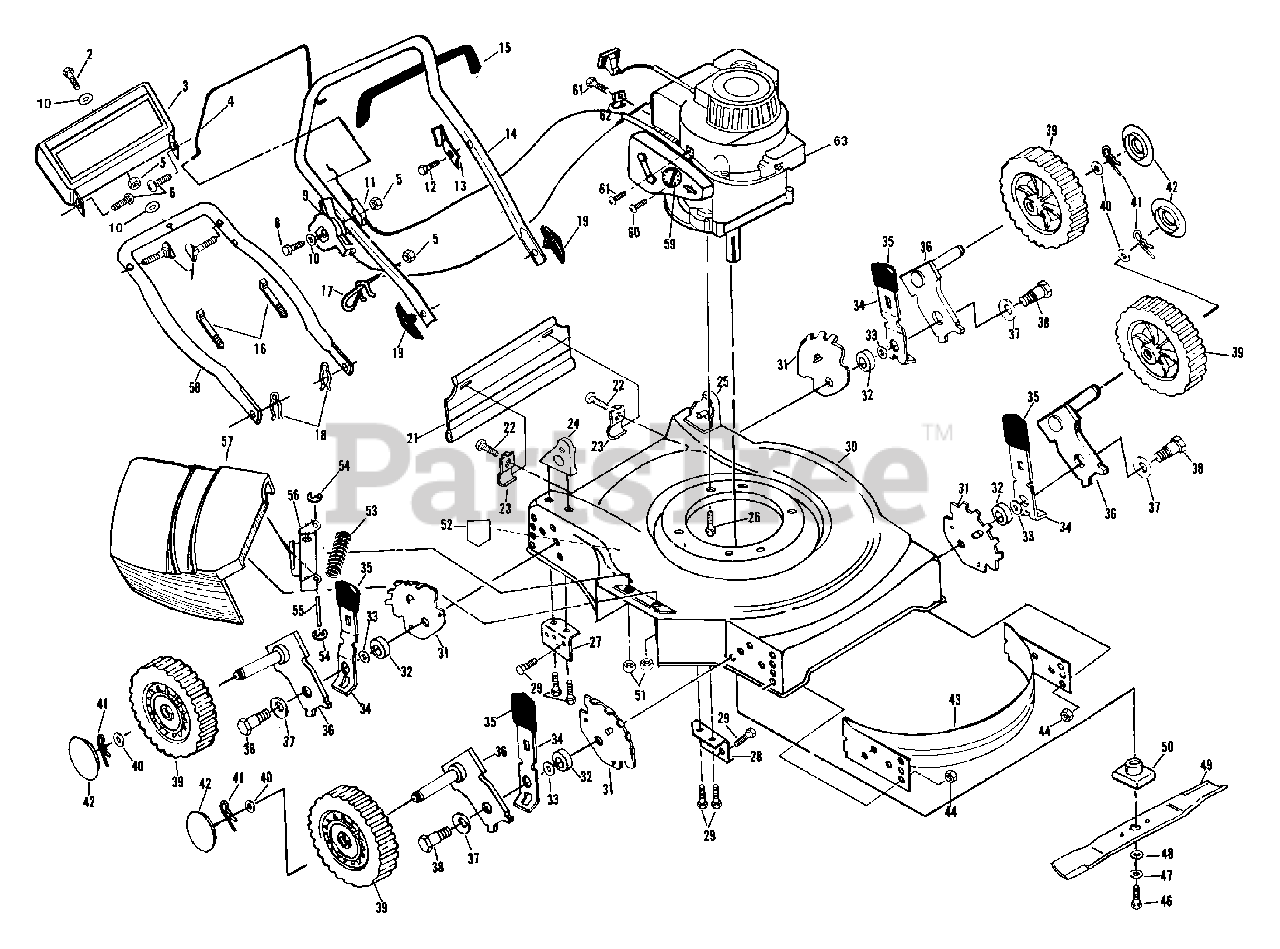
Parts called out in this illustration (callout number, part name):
2	Hex Washer Head Screw 1/4-20 x 1-1/2
3	Trim Plate
4	Control Bar
5	Locknut 1/4-20
6	Self-tapping Screw #10-24 x 5/8
7	Handle Bolt 5/16-18 x 1-3/4
8	Machine Screw 1/4-20 x 2-1/8
9	Throttle Control
11	Engine Zone Control Cable
12	Hex Washer Head Screw #10-24 x 1/2
13	Up-Stop Bracket
14	Upper Handle
15	Handle Grip
16	Wire Tie
17	Rope Guide
18	Hairpin Cotter
19	Handle Knob
21	Rear Skirt
22	Hex Washer Head Screw #10-24 x 1/2
23	Rear Skirt Bracket
24	Handle Bracket Assembly (Right)
25	Handle Bracket Assembly (Left)
26	Thread Rolling Screw 3/8-16 x 1
27	Support Handle Bracket (Right)
28	Support Handle Bracket (Left)
29	Screw 5/16-18
30	Lawn Mower Housing
31	Wheel Adjusting Bracket
32	Spacer
34	Selector Spring
35	Selector Knob
36	Axle Arm Assembly
37	Belleville Washer
38	Shoulder Bolt 3/8-16
39	Wheel Assembly 8.0 x 2.0
41	Retainer Clip
43	Front Baffle
44	Locknut 3/8-16
46	Hex Head Screw 3/8-24 x 1-3/8 Gr. 8
47	Helical Lockwasher 3/8
48	Hardened Washer
49	20" Blade
50	Blade Adapter
51	Locknut
52	Danger Decal
53	Torsion Spring
54	E-Ring
56	Housing Bracket Assembly
57	Discharge Guard
58	Lower Handle
59	Muffler Deflector
60	Screw #8-32 x 3/8
61	Thread Rolling Screw #10-32 x 5/8
62	Cable Clamp
